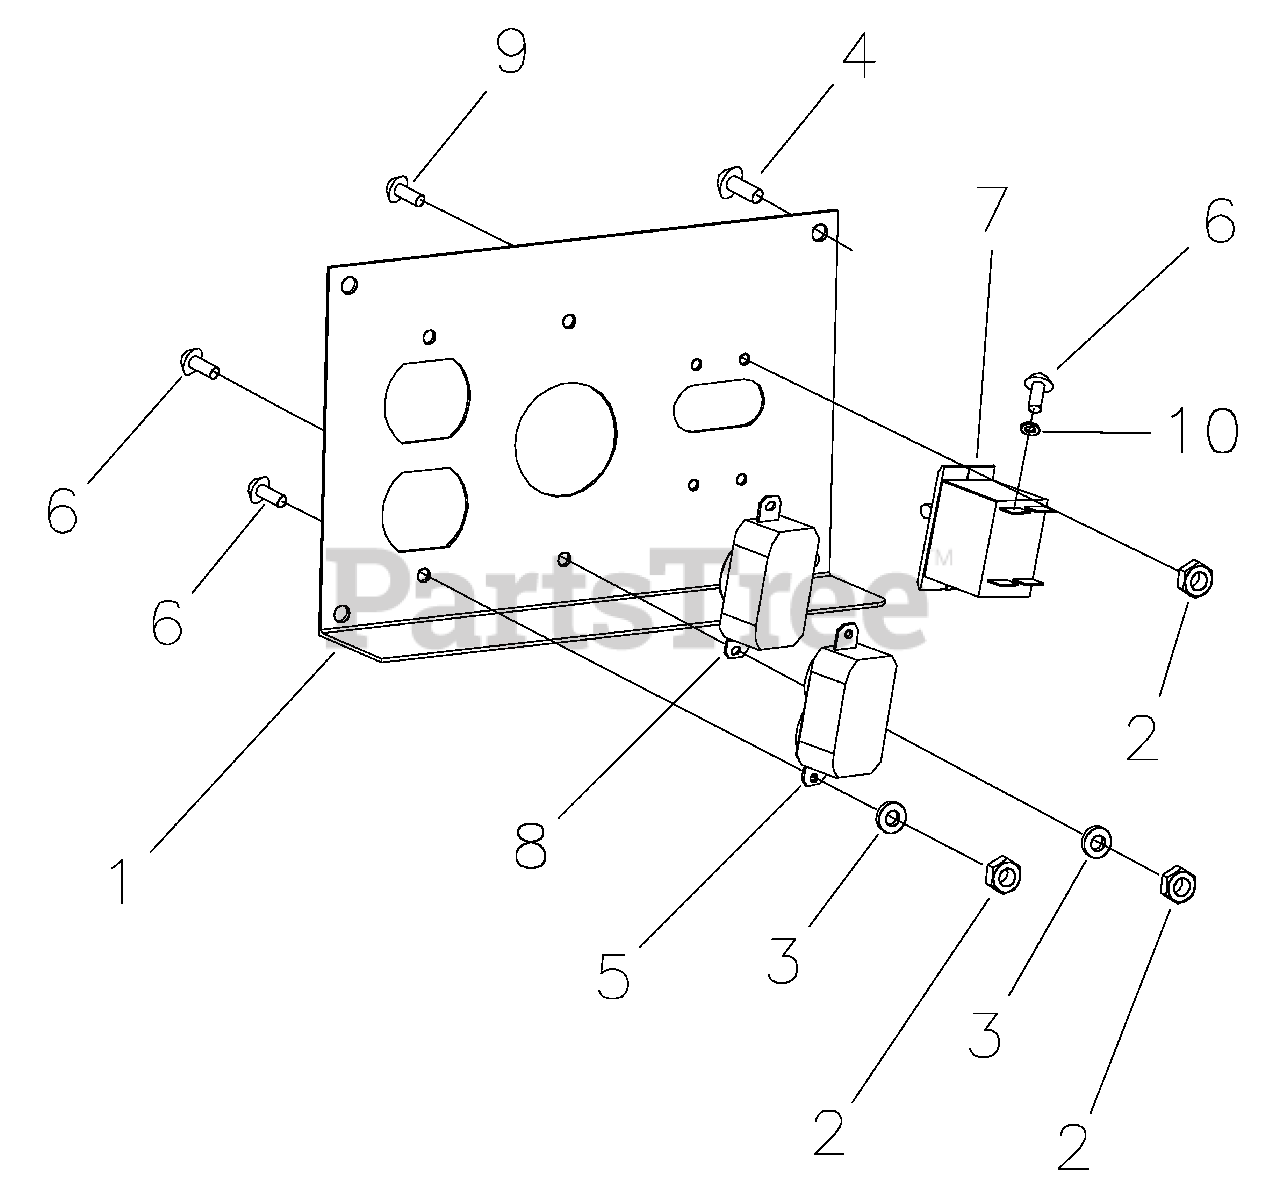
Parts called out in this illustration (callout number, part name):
2	Nut, Nylon
3	Washer, M4 x 8
4	Screw, M6 x 16
5	Outlet, 120/125V, 15/20a, Duplex
6	Screw, Pan Head, M4x10
7	Circuit Breaker, 15A
8	Outlet, 120/240V, 20a, Locking
9	Screw, M3 x 6
10	Lock Washer
